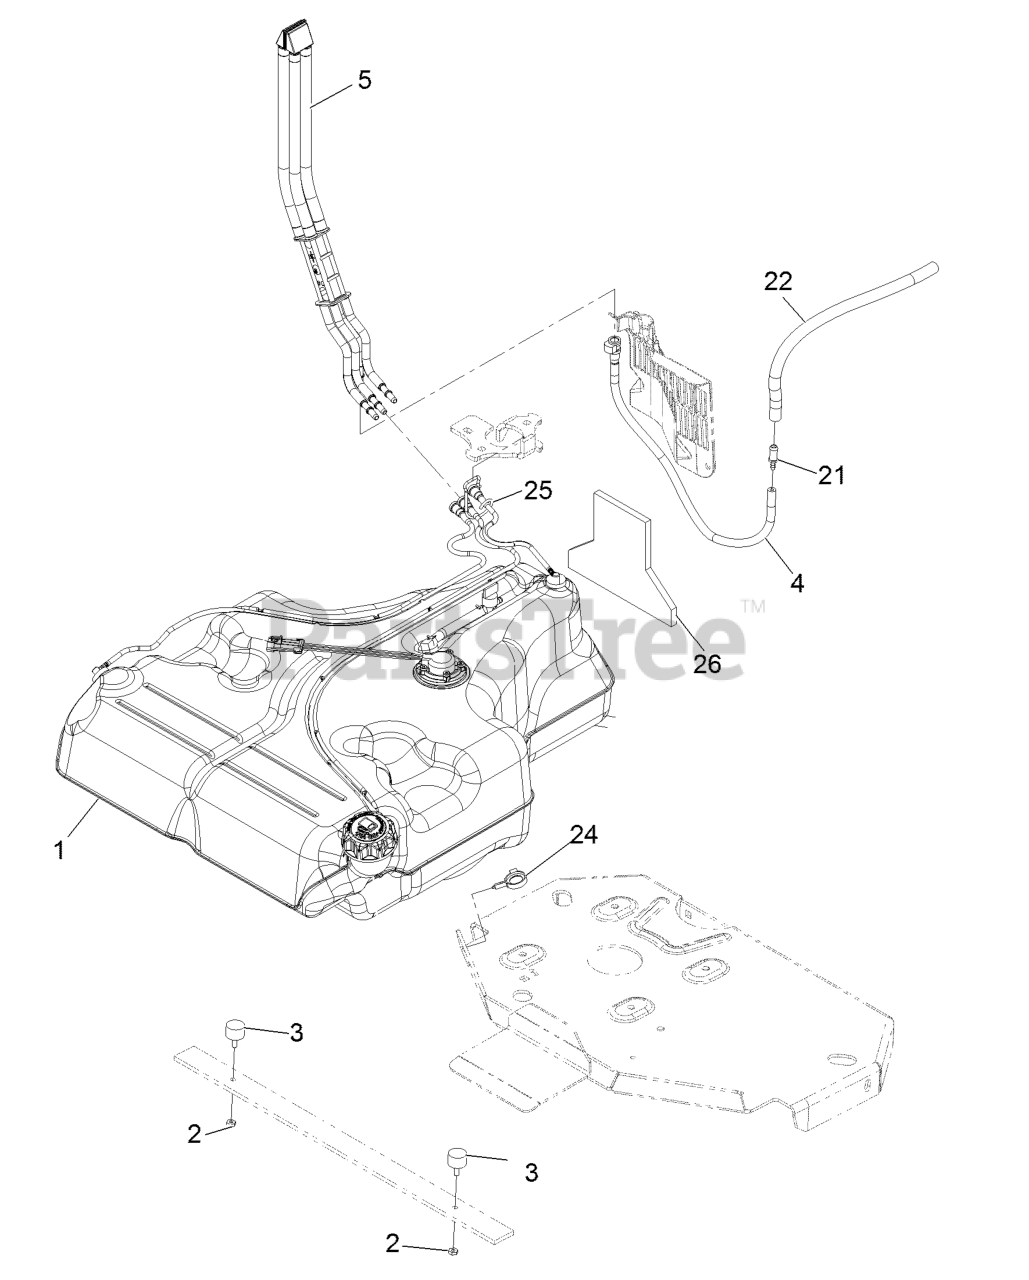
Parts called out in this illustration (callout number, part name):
2	NUT-JAM
4	HOSE ASM
5	FUEL MANIFOLD VENT ASM
21	FITTING-STRAIGHT
22	HOSE-FUEL
24	CLAMP-HOSE
25	RETAINER-LINE, VAPOR
26	INSULATION-FOAM, FUEL TAN
